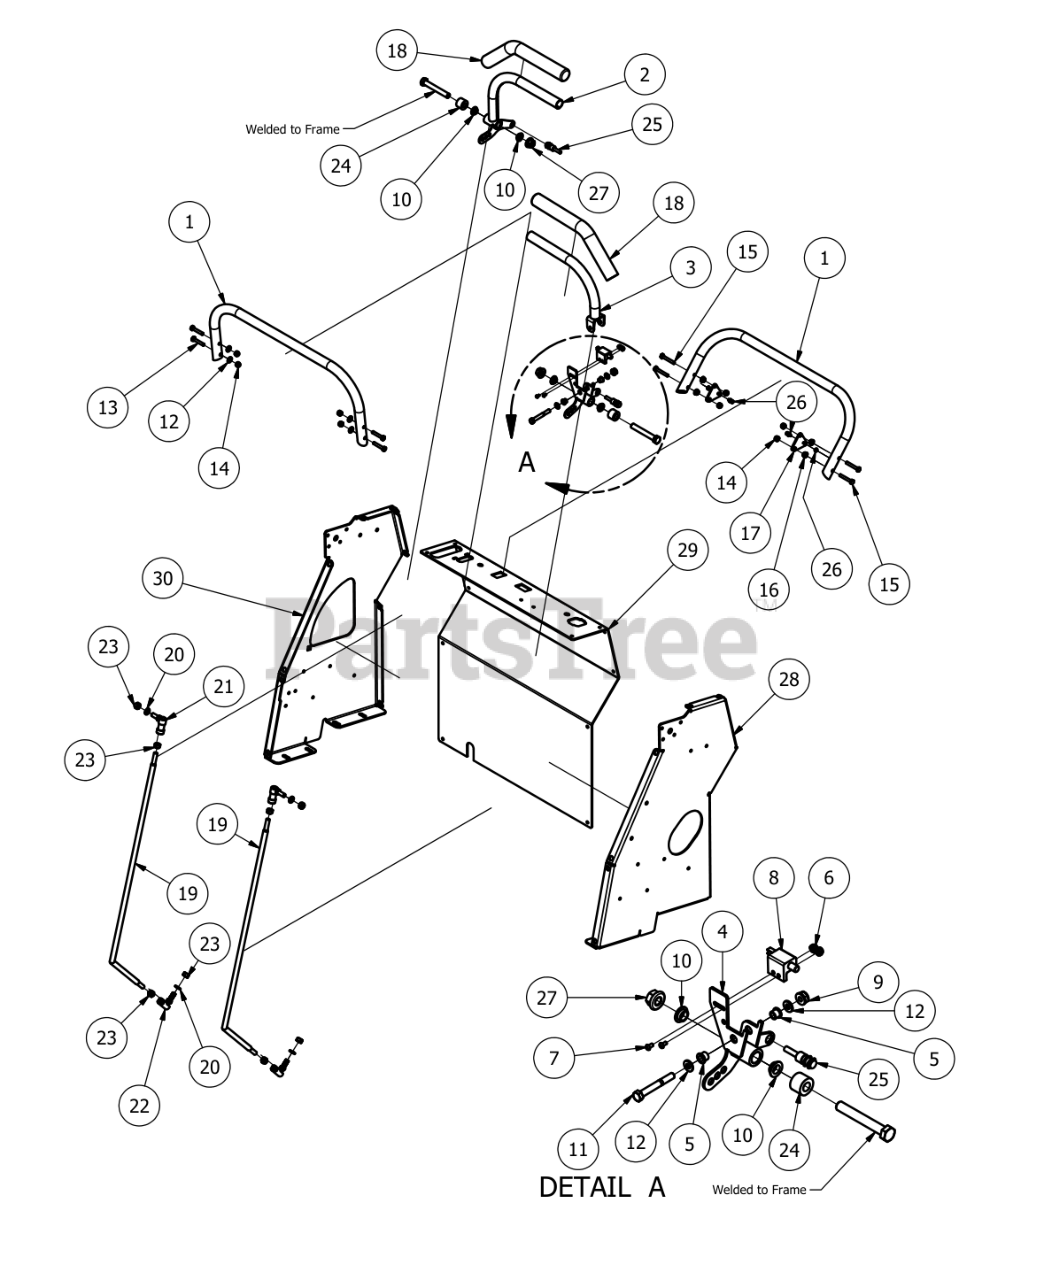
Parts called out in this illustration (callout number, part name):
1	Support Handle Stand Up (Front & Back)
2	Left Steering Handle Assembly
3	Right Steering Handle Assembly
4	Safety Kill Switch Assembly Bracket
5	Stand On Flange Bushing-Steering Arms
6	#10 Nylock Nut
7	1024 X 5/8" Buttonhead Bolt
8	Safety Switch
9	5/16-18 Nylon Flange Nut
10	Bushing for 2012 Drive Arms
11	5/16" x 2 1/2" Bolt
12	1/4" Flat Washer
13	1/4-20 x 1 1/2" Bolt
14	1/4" Nylock Nut
15	1/4-20x 1-3/4" Hex Bolt
16	1/4-20 Hex Flange Nuts Zinc w/Serrations
17	Neutral Safety Tab
18	Black Steering Grip
19	Push Rod Stand On
20	3/8" Lock Washer
21	3/8-24 Quick Release Ball Joint
22	3/8-24 Ball Joint
23	3/8" Fine Threaded Jam Nut
24	Steering Arm Spacer- Stand On
25	Safety Switch Harness
26	Magnet-Steering Arm-Stand On
27	1/2-13 Mechanical Lock Nut Grade F
28	2015 Podium Panel Right
29	2015 Podium Front Panel
30	2015 Podium Panel Left
